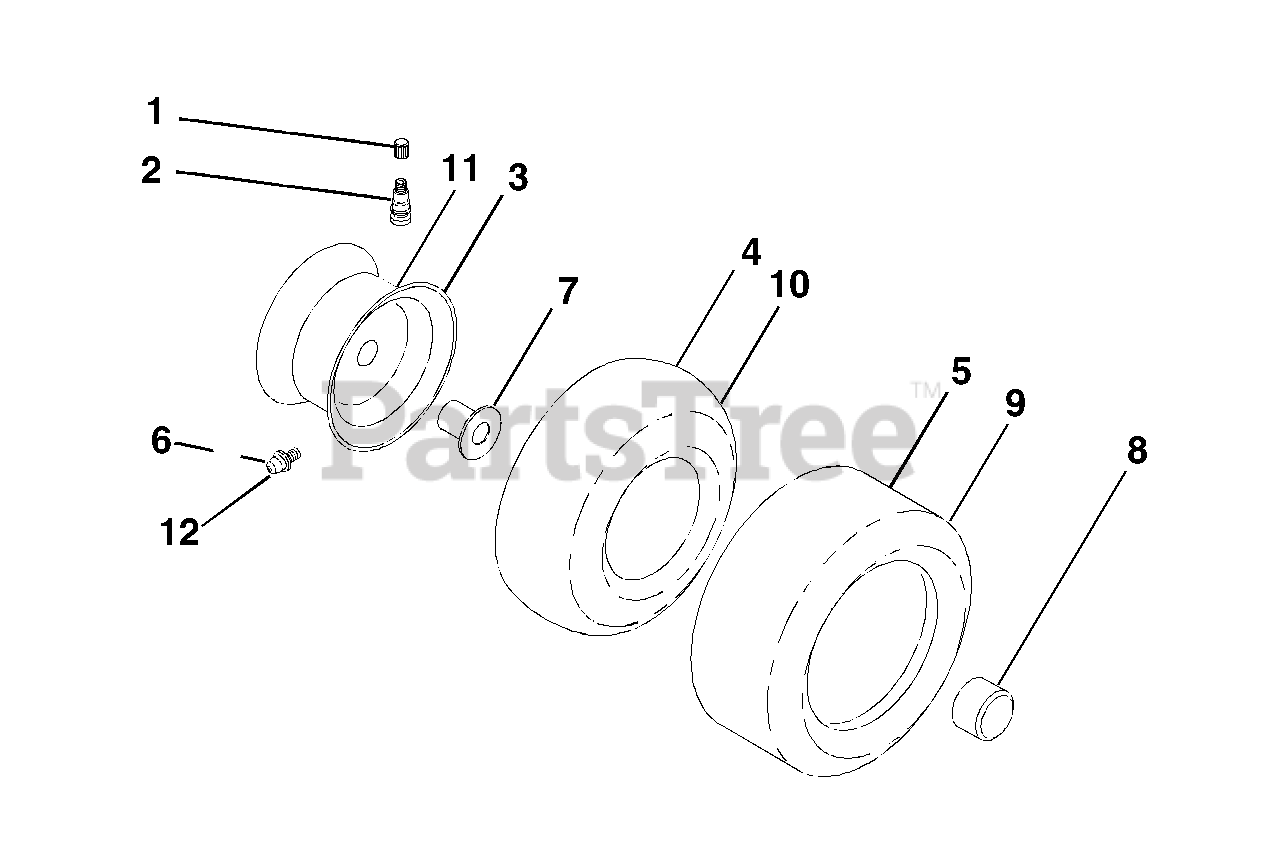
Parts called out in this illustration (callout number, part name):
1	Cap, Valve, Tire
2	Stem, Valve
3	Rim Assembly, Front
4	Tube, Front
5	Tire, Front
6	Fitting, Grease
7	Bearing, Flange
8	Cap, Hub
9	Tire, Rear
10	Tube, Rear
11	Rim Assembly, Rear
12	Fitting, Grease
